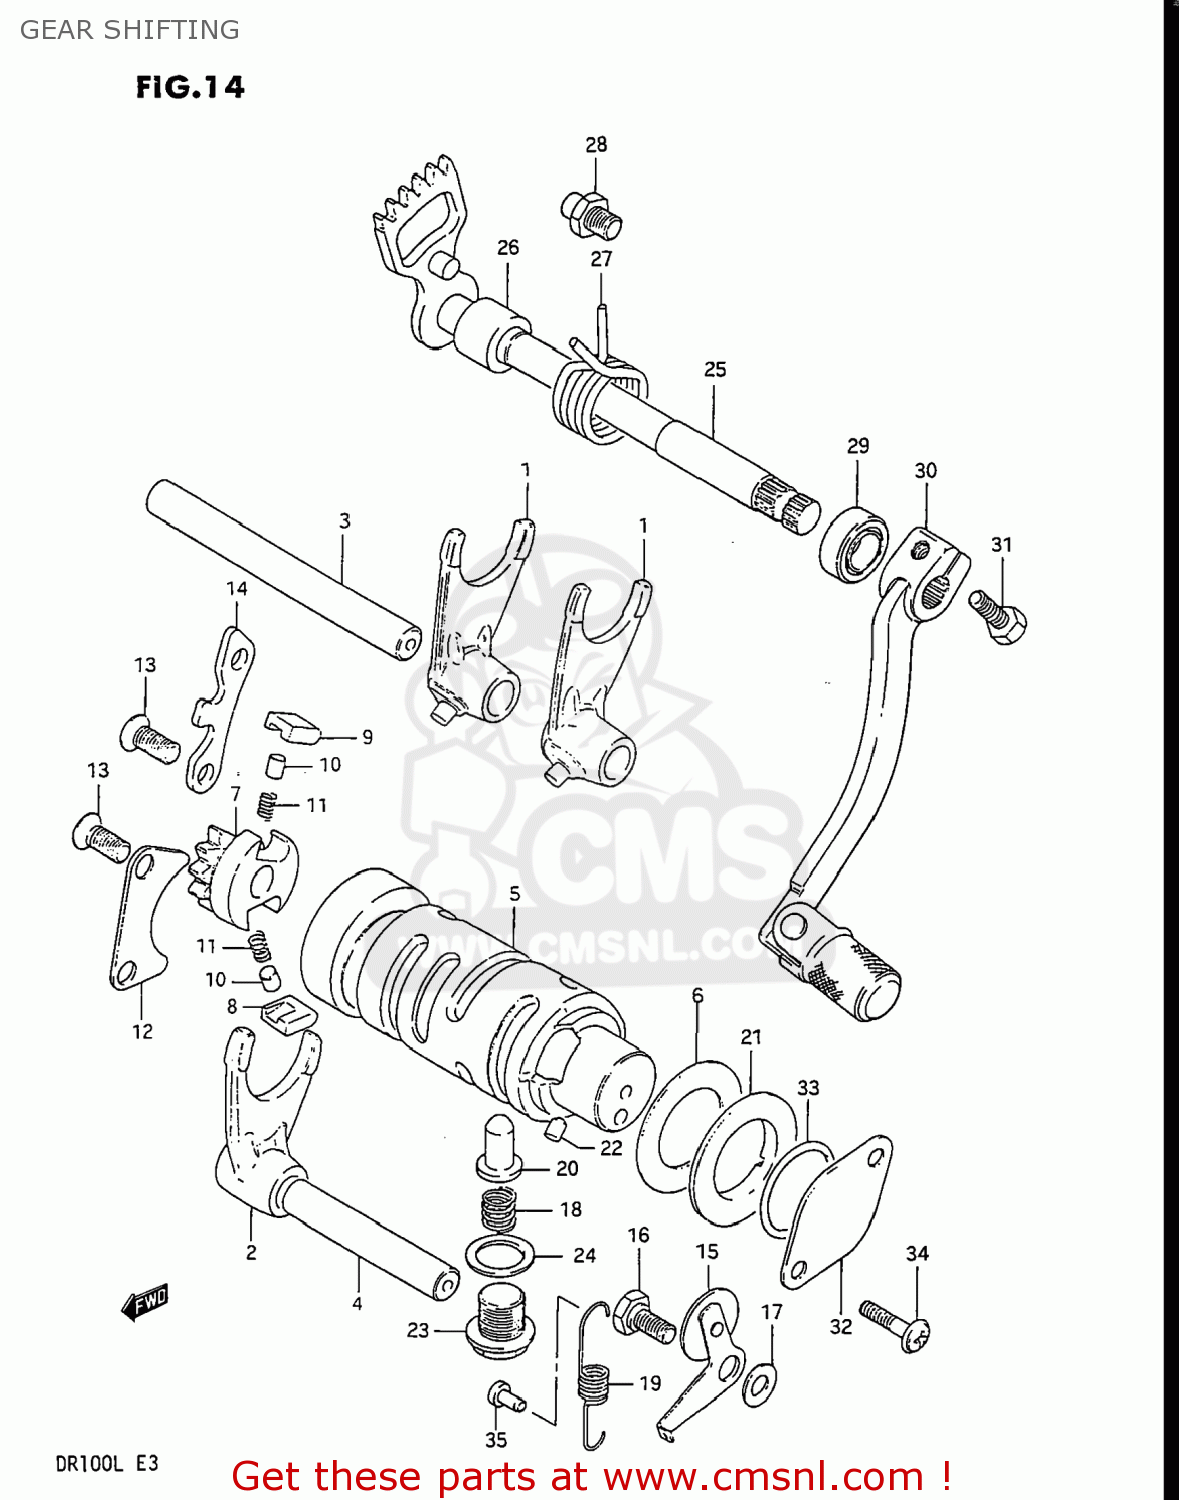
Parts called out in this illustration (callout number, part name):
1	FORK,GEAR SHIFT NO.2
2	FORK,GEAR SHIFT NO.3
3	SHAFT,GEAR SHIFT FORK(L:109)
4	SHAFT,GEAR SHIFT FORK
5	CAM,GEAR SHIFT
6	WASHER,THRUST
7	GEAR,GEARSHIFT CAM DRIVE
8	PAWL,GEAR SHIFT NO.1
9	PAWL,GEAR SHIFT NO.2
10	PIN(5X8)
11	SPRING
12	LIFTER,GEAR SHIFT POLE
13	SCREW
14	GUIDE,GEAR SHIFT CAM
15	STOPPER,GEAR SHIFTING
16	BOLT
17	WASHER
18	SPRING
19	SPRING
20	STOPPER,GEAR SHIFT CAM NO.2
21	PLATE,GEAR SHIFT CAM STOPPER
22	PIN 4X6
23	PLUG (14X12)
24	GASKET(14X19.2X2) (NAS)
25	SHAFT,GEAR SHIFT
26	SPACER(12X20X15.3)
27	SPRING
28	STOPPER,GEAR SHIFT CAM
29	OIL SEAL
30	LEVER ASSY,GEAR SHIFT
31	BOLT
32	CAP,GEAR SHIFT CAM PIVOT
33	O-RING (D:2.4 ID:26.2)
34	SCREW
35	RIVET
